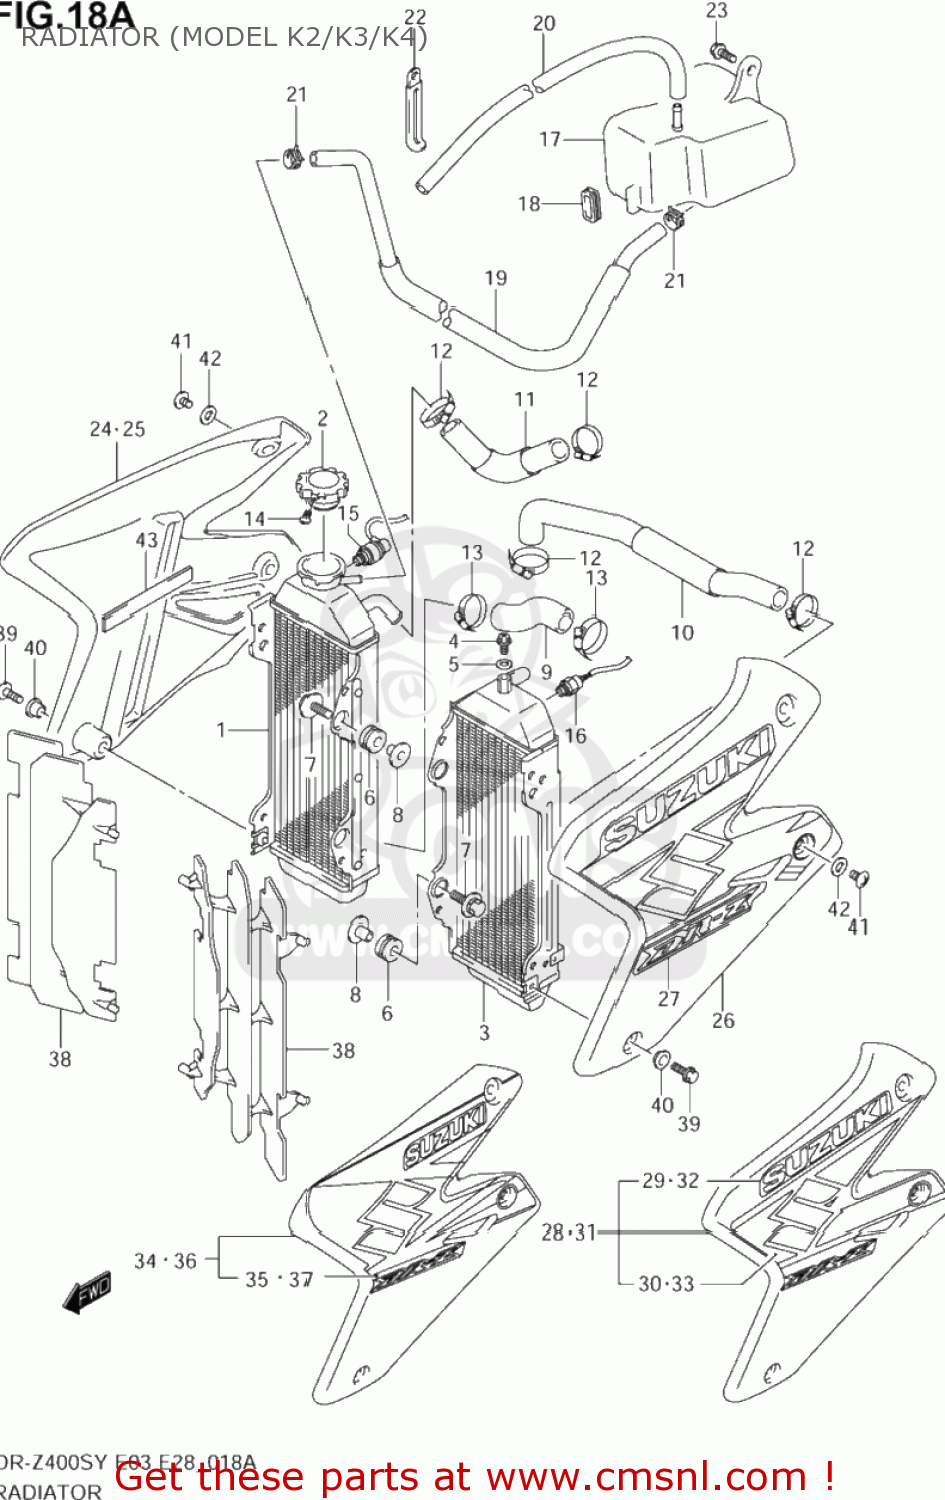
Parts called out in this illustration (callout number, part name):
1	RADIATOR COMP,WATER,RIGHT
2	CAP,RADIATOR(1.1)
3	RADIATOR COMP,WATER,LEFT
4	UNION BOLT,AIR VENT
5	GASKET(6.4X11.5X0.8) (NAS)
6	CUSHION,RADIATOR LWR
7	BOLT(6X25)
8	SPACER(6.5X10.5X14.1)
9	HOSE,RADIATOR INLET
10	HOSE,RADIATOR OUTLET
11	HOSE,RADIATOR JOINT
12	CLAMP
13	CLAMP
14	SCREW,RADIATOR CAP
15	SWITCH ASSY,WATER TEMP
16	SWITCH,FAN
17	TANK,RESERVOIR
18	CUSHION,RESERVOIR TANK
19	HOSE,RESERVOIR TANK INLET
20	HOSE(5X9X2000)
21	CLIP
22	CLAMP(L:65)
23	BOLT
24	COVER,RADIATOR,R
25	TAPE SET,RADIATOR COVER,R
26	COVER,RADIATOR,L
27	TAPE SET,RADIATOR COVER,L
28	COVER,RADIATOR,R(BLUE)
29	EMBLEM,SUZUKI
30	TAPE,RADIATOR COVER,R
31	COVER,RADIATOR,L(BLUE)
32	EMBLEM,SUZUKI
33	TAPE,RADIATOR COVER,L
34	COVER,RADIATOR,R
35	TAPE,RADIATOR COVER,R
36	COVER,RADIATOR,L
37	TAPE,RADIATOR COVER,L
38	LOUVER,RADIATOR
39	SCREW
40	WASHER
41	SCREW
42	WASHER
43	CUSHION,COVER SIDE
